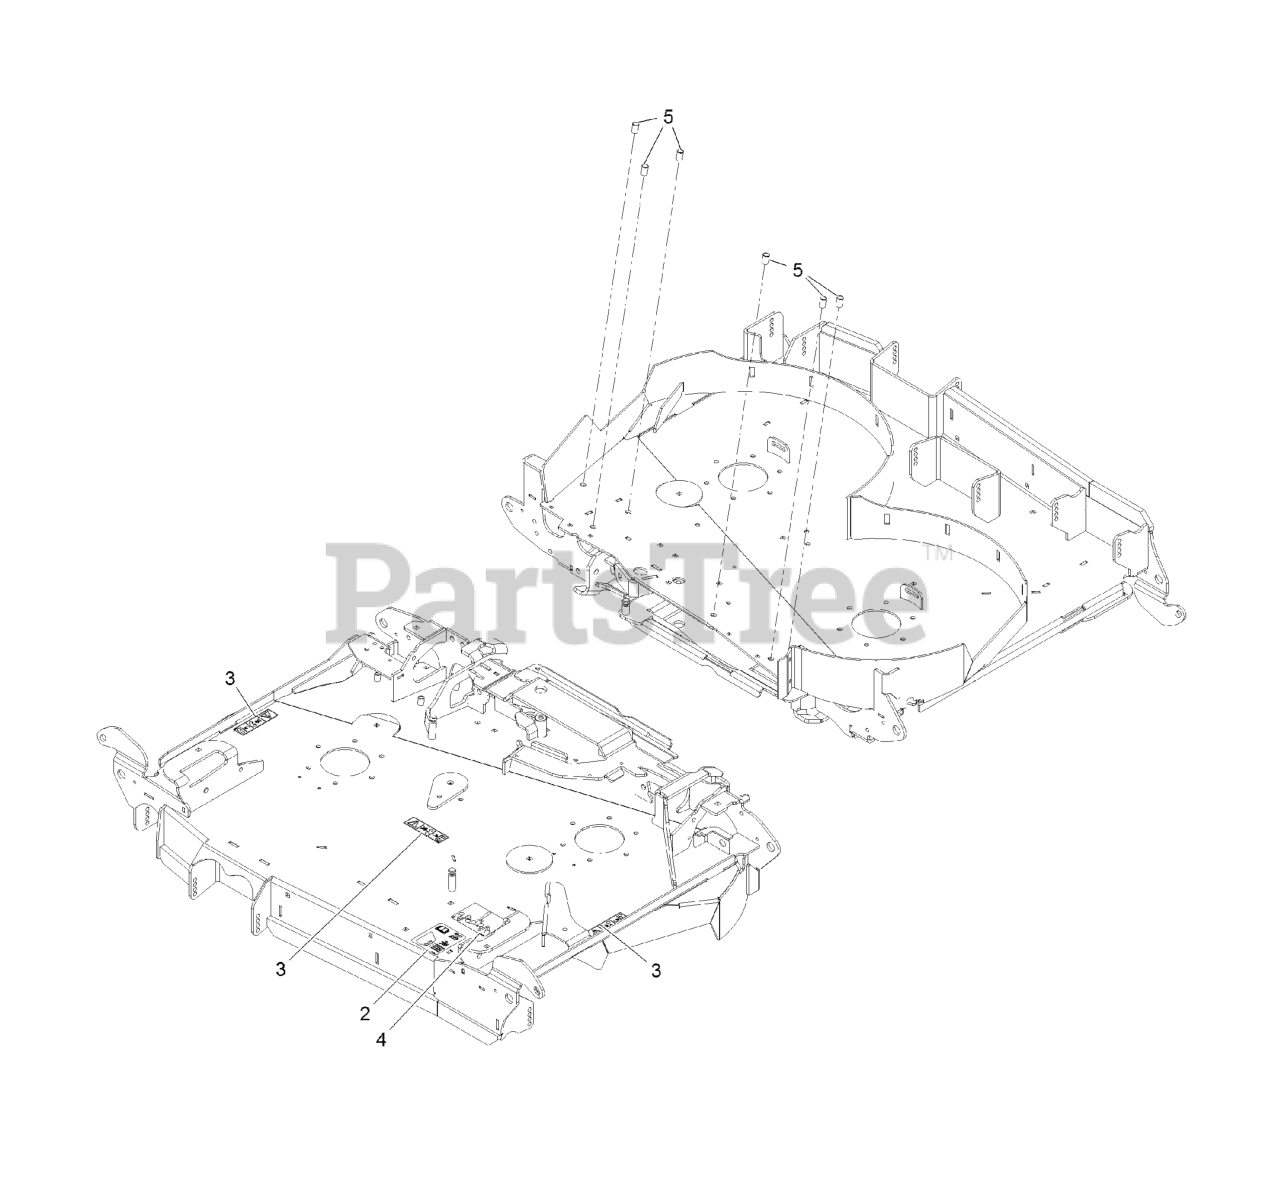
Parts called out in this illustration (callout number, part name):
2	DECAL-ROLLER, ANTI-SCALP
3	DECAL-COVER, MISSING
4	Decal-Belt Routing
5	NUT-CLINCH
